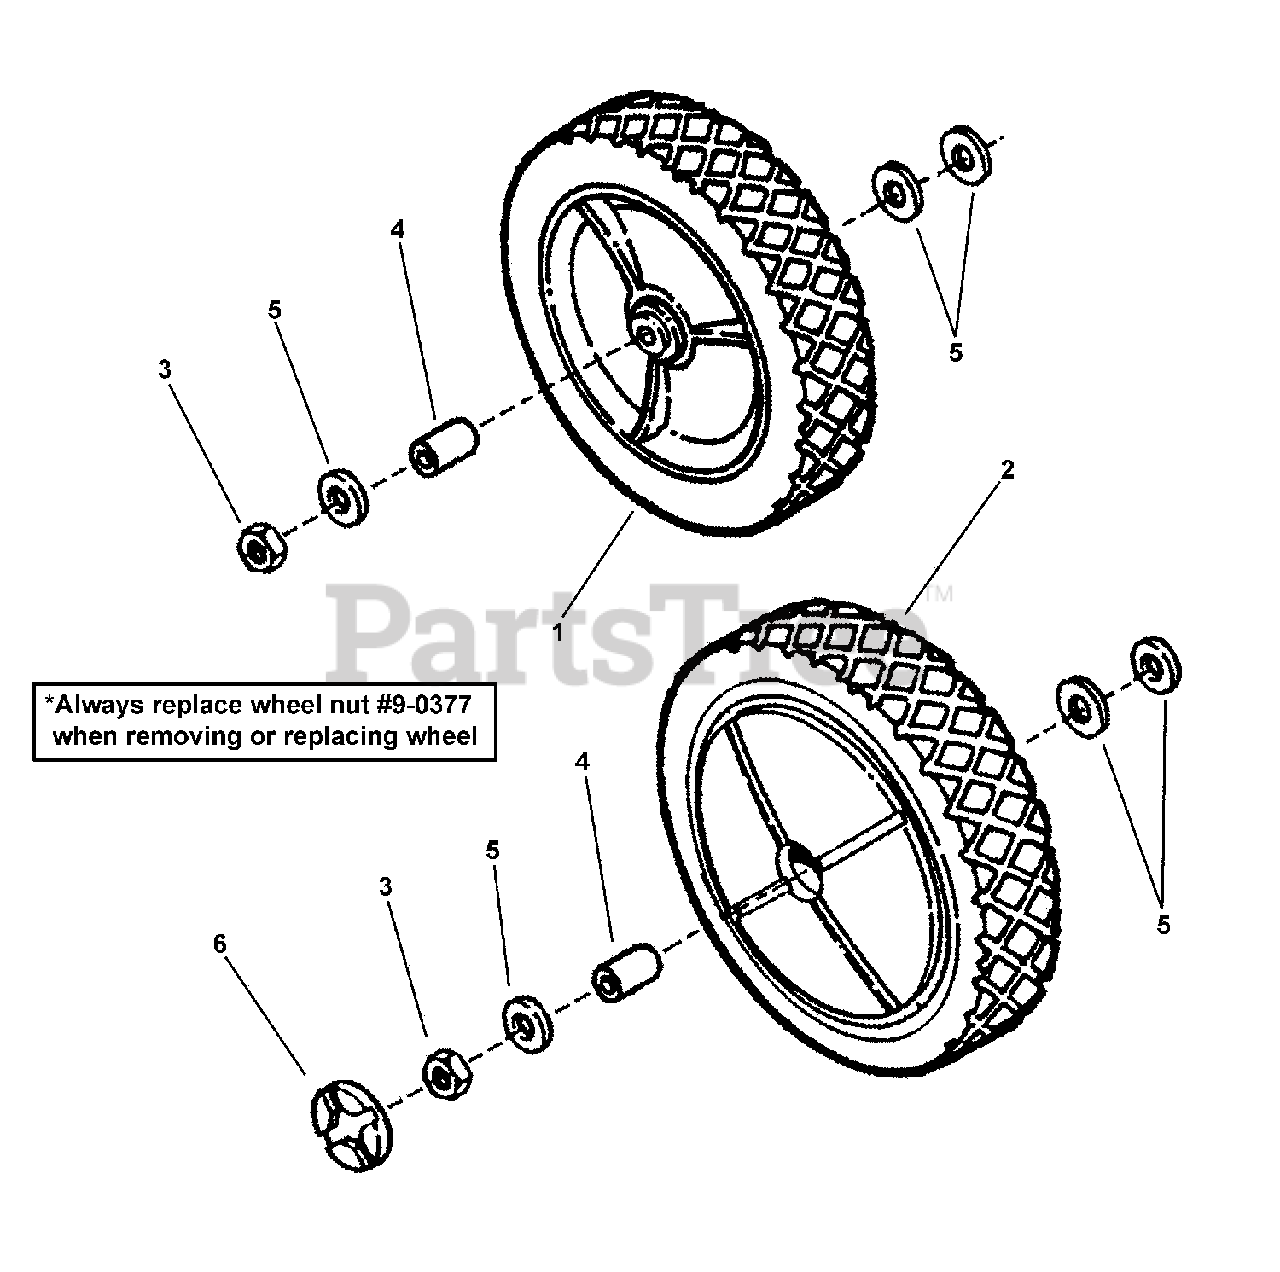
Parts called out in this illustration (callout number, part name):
1	WHEEL, 8 x 1.75 Plastic
2	WHEEL, 8 x 1.75 Plastic
3	NUT, 7/16-20 Hex Center Lock Jam
4	BUSHING, Axle
5	WASHER, 7/16 x 1" O.D. Flat
6	PLUG, Wheel
